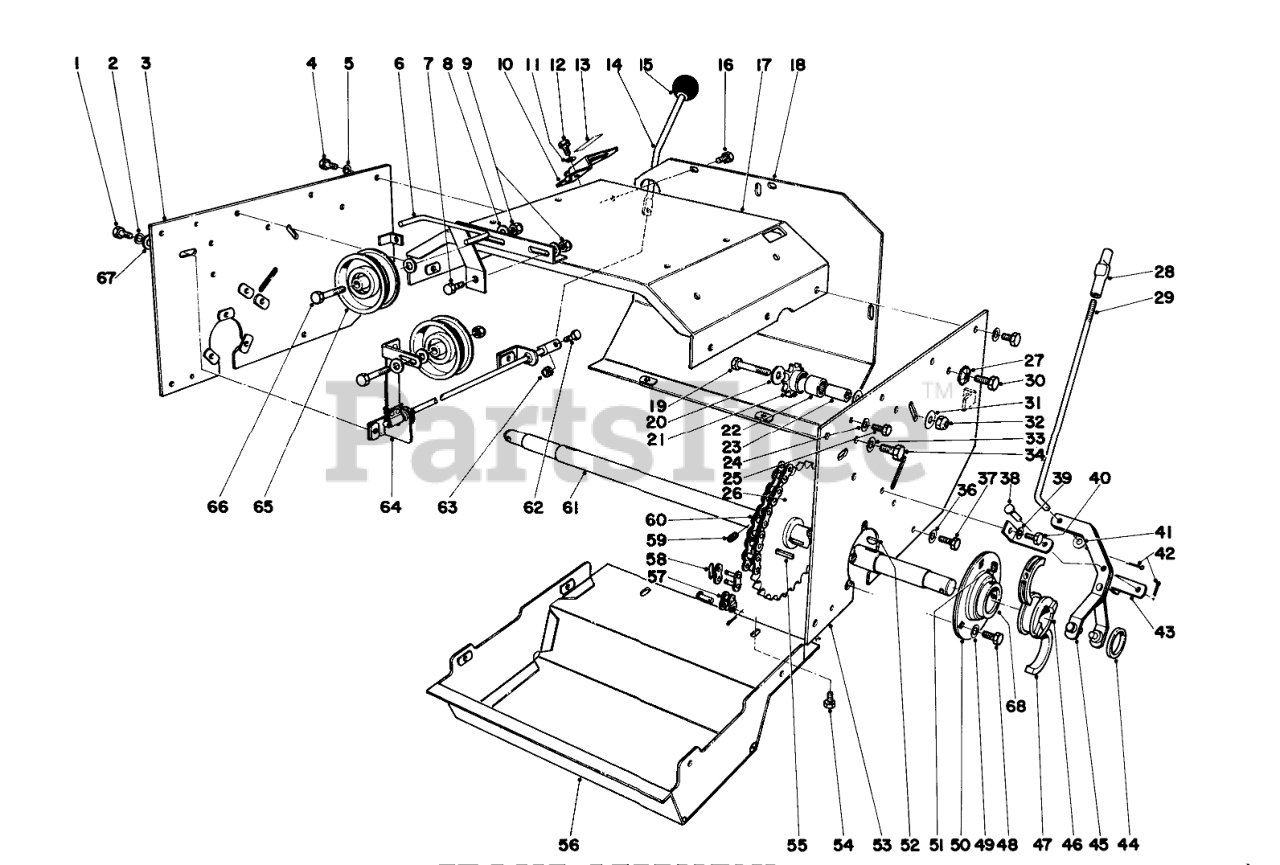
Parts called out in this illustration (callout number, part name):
1	SCREW-HH
2	WASHER-LOCK
3	Drive Side Plate
4	SCREW-HH
5	WASHER-LOCK
6	Belt Guide
7	SCREW-HH
8	WASHER-FLAT
10	Selector Plate-Clutch
11	WASHER-LOCK
12	SCREW-HH
13	Decal-Clutch Control
14	Control-Belt Clutch
15	BALL-GRIP
16	1/4-20 X 1/2 SEMS MS
17	Engine Base
18	Rear Shield
19	SCREW-HH
20	WASHER-FLAT
21	SPROCKET & BRG ASM
22	Bearing
23	SPINDLE
24	WASHER-LOCK
25	SCREW-HH
26	Sprocket
27	LOCKWASHER-PYRAMID
28	Turnbuckle-Wheel Clutch
29	Lower Rod-Wheel Clutch
30	SCREW-HH
31	WASHER-FLAT
32	NUT-LOCK, NI
33	WASHER-LOCK
34	SCREW-HH
36	WASHER-LOCK
37	SCREW-HH
38	PIN-CLEVIS
39	WASHER-LOCK
40	SCREW-HH
41	WASHER-FLAT
42	PIN-COTTER
43	Bracket-Fork Pivot
44	Spacer
46	Sliding Jaw
48	SCREW-HH
49	WASHER-LOCK
50	Bearing Flange
51	SCREW-SET, HSH
52	KEY-WOODRUFF
53	Drive Side Plate
54	1/4-20 X 1/2 SEMS MS
56	Lower Shield
57	1/4 OFFSET LINK
58	LINK-CONNECTING
59	SCREW-SET, HSH
60	Chain (Incl. Ref. #57 & 58)
61	Axle Drive
62	SCREW-HH
63	NUT-LOCK, NI
64	Belt Clutch
65	Pulley Idler
66	SCREW-HH
67	WASHER-FLAT
68	Collar
